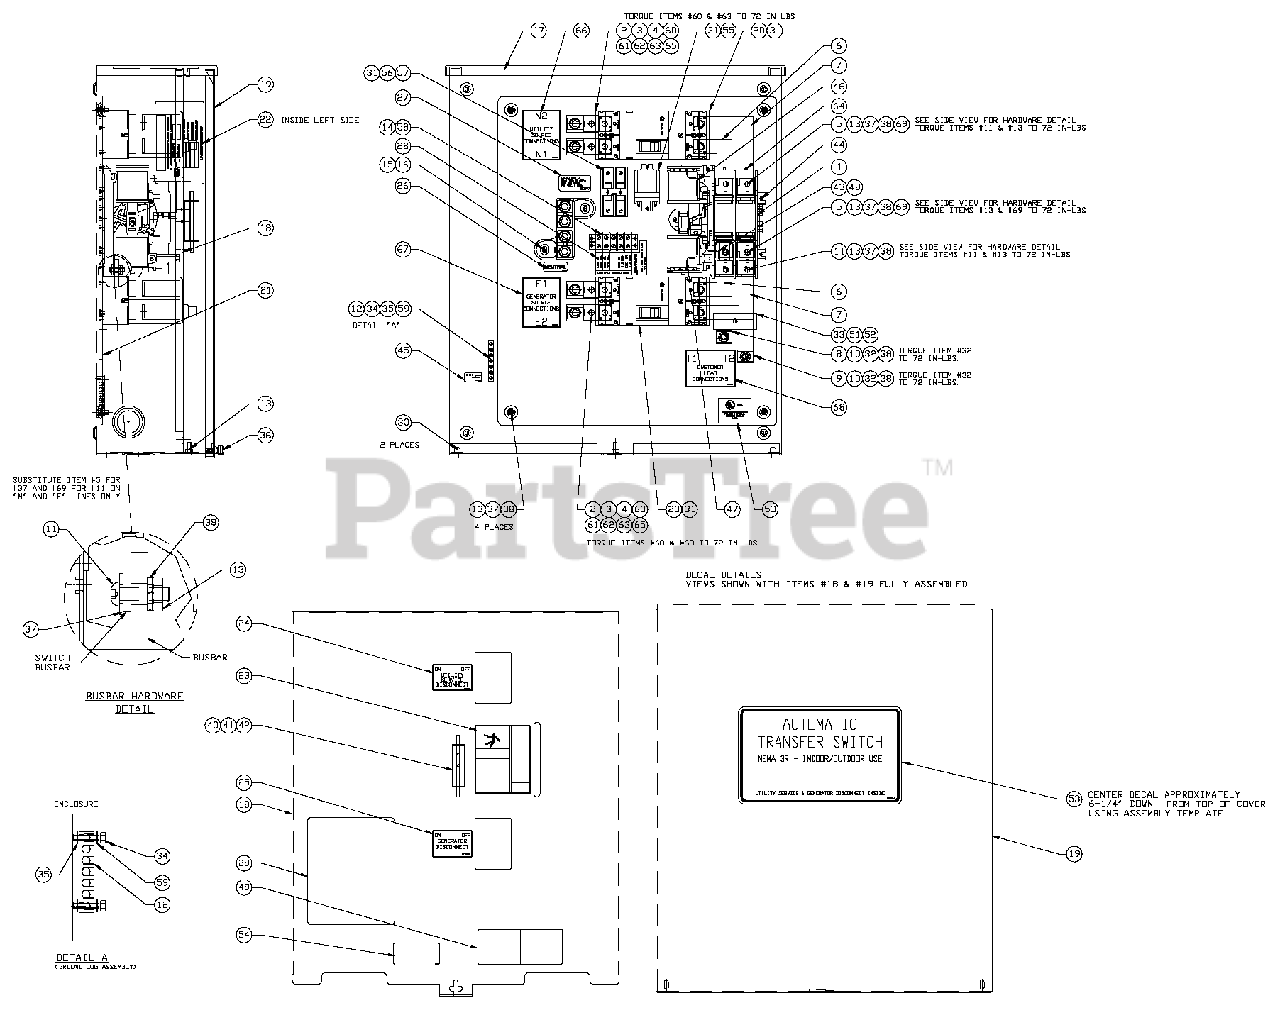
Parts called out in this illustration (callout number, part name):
1	TRANSFER SW. HSB 200A 2P 250V
2	CIRCUIT BREAKER, 200A 2-POLE
3	BUSBAR, 200A LUG ADAPTER
4	LUG 300 MCM-6STR
5	SPACER 200 AMP TRANSFER
6	BUSBAR, 200A HSB XFER SW N1-E1
7	BUSBAR, 200A HSB XFER SW N2-E2
8	BUSBAR, 200A HSB XFER SW T1
9	BUSBAR, 200A HSB XFER SW T2
10	LUG SOLDERLESS 250-#6 AL/CU
11	SCREW BHSC 1/4-20 X 3/4"
12	GROUND BAR (5) 4-14 AWG CONN
13	NUT HEX 1/4-20 SS
14	RIVET, POP .156 X .67
15	ASS'Y NEUTRAL BLOCK 200A
16	SCREW HHTT M6-1.0 X 12 MM
17	ENCLOSURE, 200A SE XFER SW
18	COVER, INSIDE 200A DUAL BREAKER
19	COVER, TRANSFER SWITCH
20	RISER, CIRCUIT BREAKER
21	SUBPLATE, 200A SE XFER SW
22	DECAL, DATA
23	DECAL, MANUAL OPERATING HANDLE
24	DECAL, UTILITY DISCONNECT
25	DECAL, GENERATOR DISCONNECT
26	DECAL, NEUTRAL
27	DECAL, FUSE REPLACEMENT
28	DECAL, TERMINAL STRIP
29	DECAL, TEST SEQUENCE
30	NUT TRIC 1/4-20 X .525
31	SCREW HHTT M4-.7 X 10 BP
32	SCREW BHSC 1/4-20X1/2
33	SCREW HHTT M6-1.0 X 35 YC
34	NUT HEX LOCK M4-0.7 SS NYL INS
35	WASHER SHAKEPROOF EXT #8 STEEL
36	THUMB SCREW 1/4-20x1/2
37	WASHER FLAT 1/4-M6 ZINC
38	WASHER LOCK M6-1/4
40	BRACKET, ARM EXTENDER
41	RIVET POP .156 X .362 AL
42	ARM EXTENDER PIN
43	90%%D LOWER SPADE CONNECTOR
44	SCREW HHTT M5-0.8 X 10 BP
45	DECAL, GROUNDING LUG
48	WIRE-E1
49	DECAL TERMINAL SHOCK HZD BI
50	DECAL-UL LIST HSB
51	BLOCK, BUSBAR COVER
52	BLOCK, BUS BAR
53	DECAL,FRNT CVR ATS 3R SER DIS
54	DECAL LIVE CIRCUIT ENG/FRN/SPN
55	RELAY PNL 12VDC DPDT
56	FUSEBLOCK 30A 600V 2 POLE
57	FUSE 5A X BUSS HLDR73591
58	BLOCK TERM 20A 5 X 6 X 1100V
59	WASHER FLAT M4
60	SCREW SHC M8-1.25 X 20 G8
61	WASHER FLAT 5/16-M8 ZINC
62	WASHER LOCK M8-5/16
63	NUT HEX M8-1.25 G8 CLEAR ZINC
64	SCREW HHTT #8-32 X 1/4 CZ
65	SCREW RHM #8-32 X 3-1/2
66	DECAL,UTILITY SOURCE CONN
67	DECAL,GENERATOR SOURCE CONN
68	DECAL,CUSTOMER LOAD CONN
69	BOLT CARR 1/4-20 X 1"
